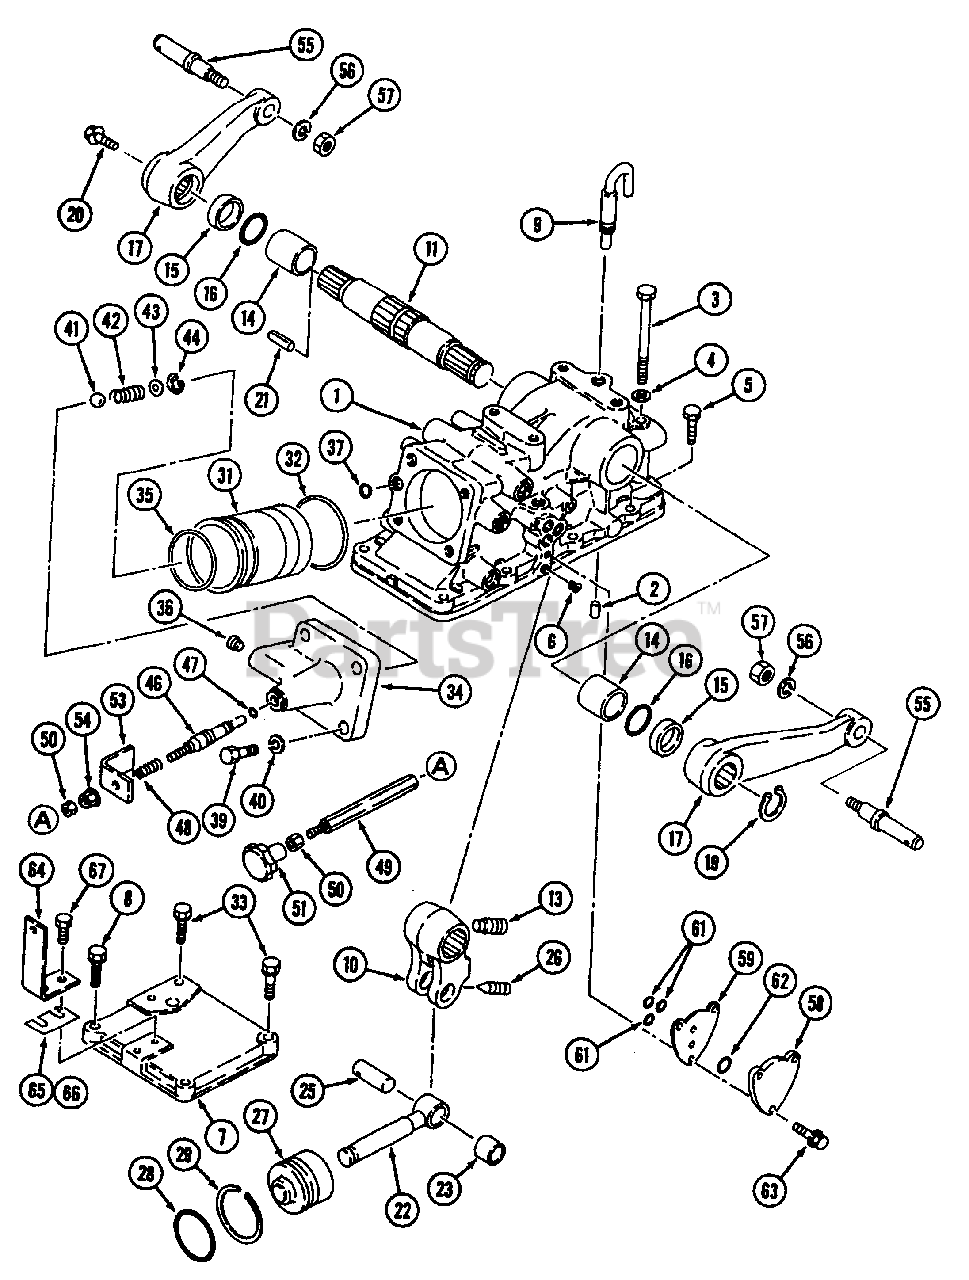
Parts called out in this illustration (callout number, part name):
1	Case, Hydraulic
11	Shaft, Hydraulic
29	Ring, Back Up
31	Cylinder, Hydraulic
34	Head, Cylinder
53	Lever, Stopper
55	Pin, Lift Arm
